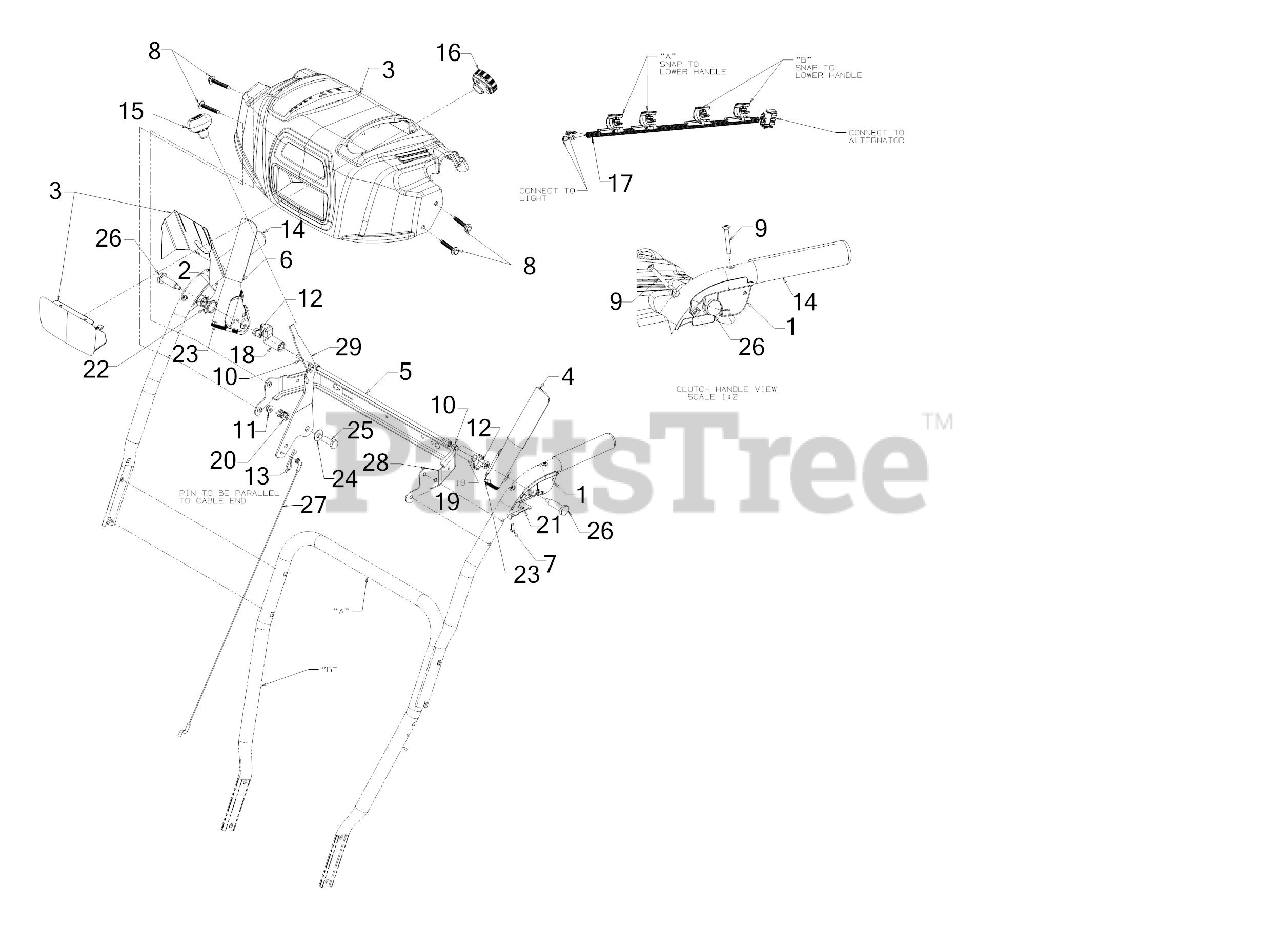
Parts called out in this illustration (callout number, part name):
1	CLUTCH LOCK HANDLE ASSEMBLY (LH)
2	CLUTCH LOCK HANDLE ASSEMBLY (RH)
3	HANDLE PANEL ASSEMBLY (CRAFTSMAN)
4	HANDLE ASSEMBLY (LH)
5	PIVOT ROD
6	ENGAGEMENT HANDLE ASSEMBLY (RH) (BLACK)
7	SCREW #8-16 x .50
8	SCREW 1/4-20 x 1.625
9	SCREW #10-24 x 1.375
10	SCREW 1/4-20 x .50
11	FLANGE LOCK NUT
12	HEX NUT W/PATCH
13	INTERNAL COTTER PIN
15	SHIFT KNOB
16	HEADLIGHT ASSEMBLY
17	LIGHT HARNESS
18	LOCK PLATE
19	CLUTCH LOCK CAM
20	COMPRESSION SPRING
21	CLUTCH SPRING
22	TORSION SPRING
23	RUBBER BUMPER
24	FLAT WASHER
25	SHOULDER SCREW
26	SHOULDER SCREW .437 x 1.345 1/4-20
27	SPEED SELECTOR CABLE (PLASTIC)
28	HANDLE SUPPORT BRACKET
29	SHIFT LEVER
